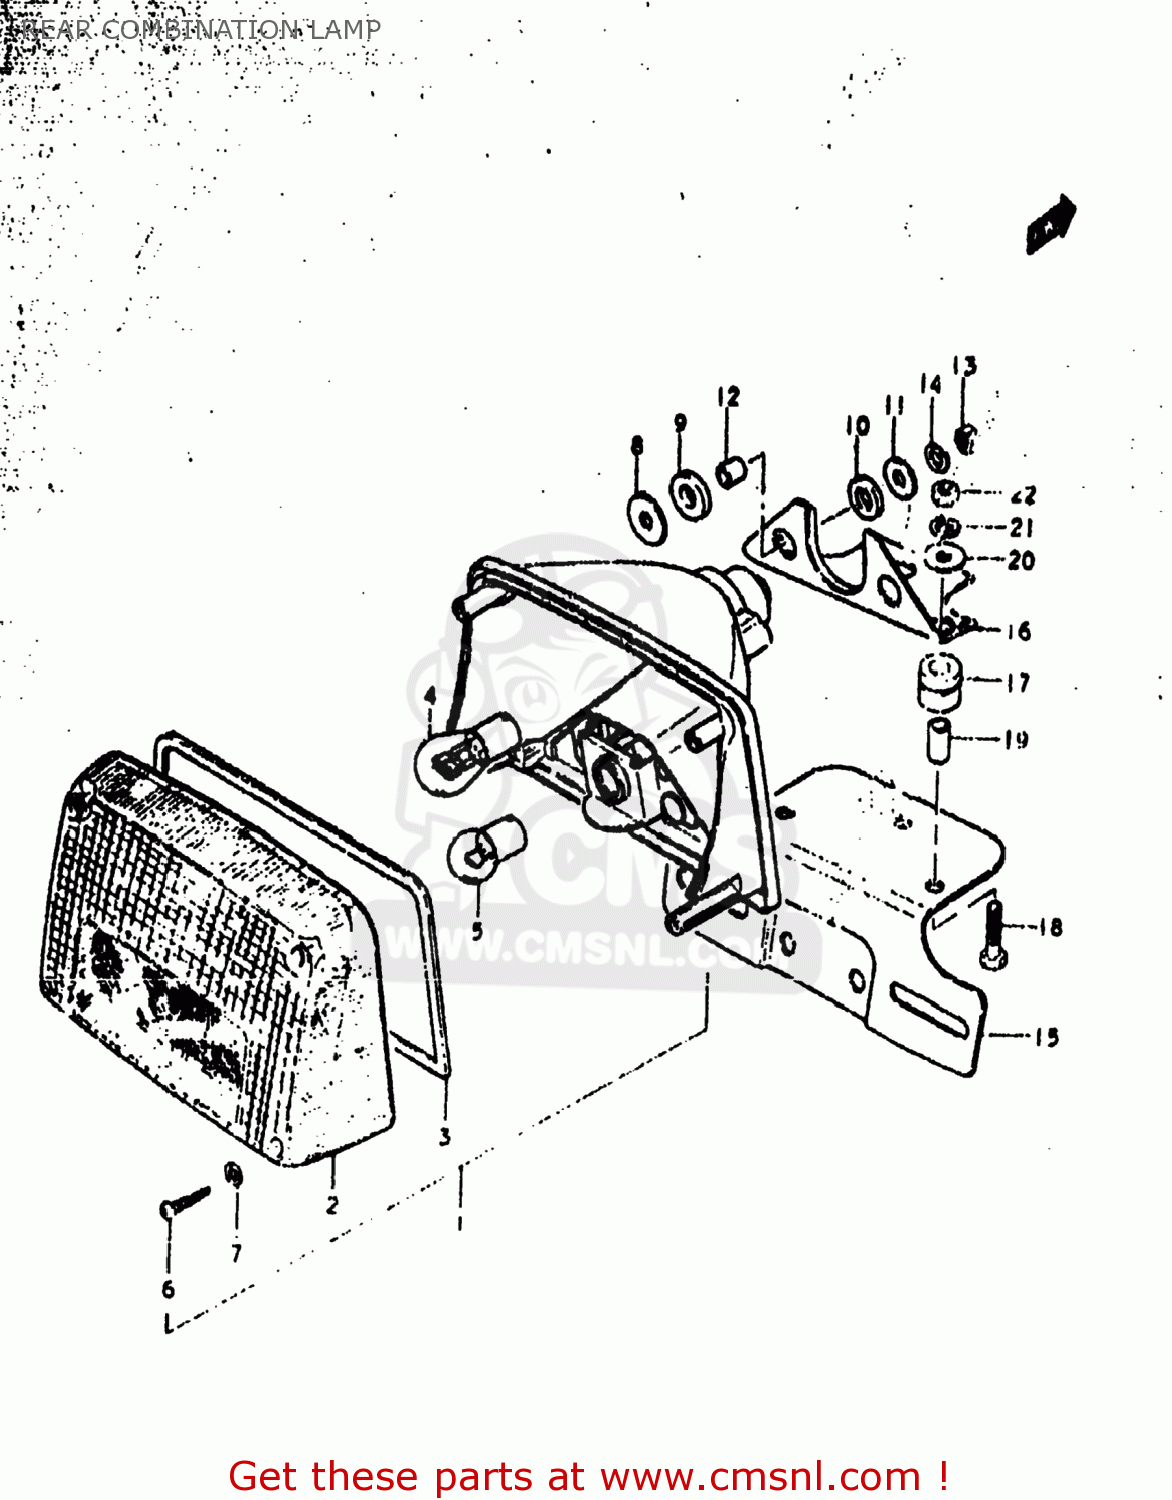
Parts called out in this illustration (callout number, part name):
1	LAMP ASSEMBLY,REAR COMBINATION
2	LENS,REAR COMBINATION LAMP
3	GASKET (NAS)
4	BULB(12V23W)
5	BULB
6	SCREW
7	GASKET (NAS)
8	WASHER
9	CUSHION
10	CUSHION
11	WASHER (6.5X24X1.6)
12	SPACER(6.1X9X7.5)
13	NUT
14	LOCK WASHER
15	BRACKET,LICENSE PLATE
16	BRACKET,LICENSE PLATE
17	CUSHION, BRACKET
18	BOLT
19	SPACER (6.1X8X15.5)
20	WASHER
21	LOCK WASHER
22	NUT
